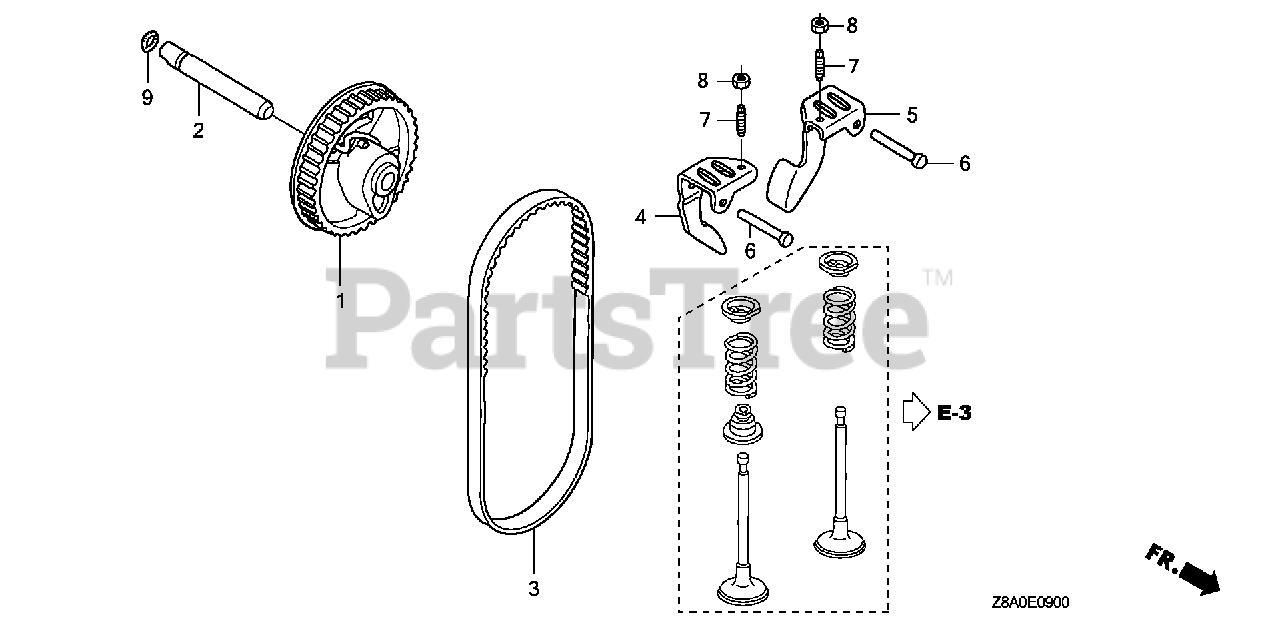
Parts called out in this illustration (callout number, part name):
1	PULLEY, CAMSHAFT
2	SHAFT, CAM PULLEY
3	BELT, TIMING (84HU7 G-200)
3	BELT, TIMING (84HU6 G-200)
4	ARM, IN. VALVE ROCKER
5	ARM, EX. VALVE ROCKER
6	SHAFT, ROCKER ARM
7	SCREW, TAPPET ADJUSTING
8	NUT, TAPPET ADJUSTING
9	O-RING (6.8X1.9) (ARAI)
